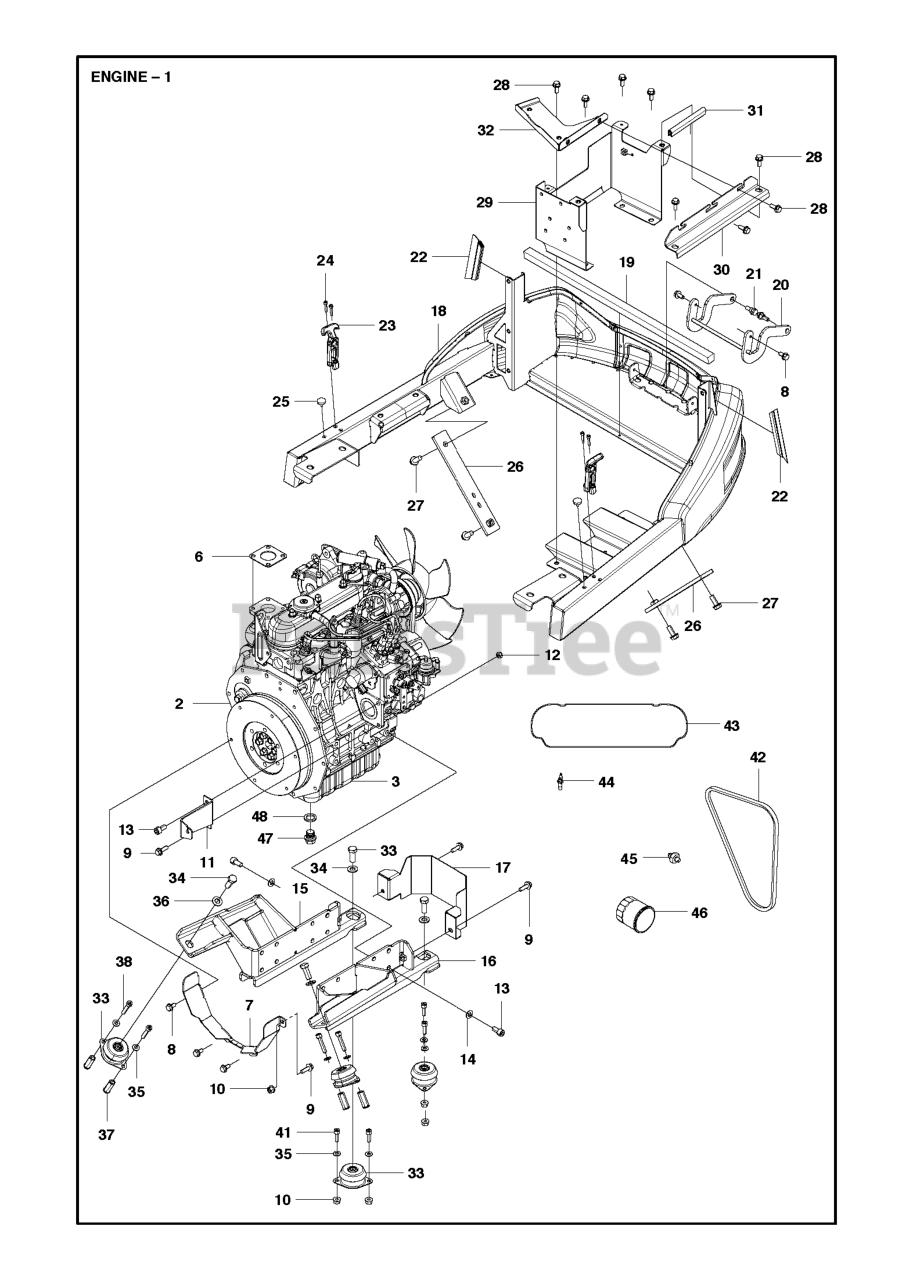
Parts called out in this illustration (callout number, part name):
9	BOLT
10	NUT FLANGE
12	LOCKNUT M8
14	WASHER
24	SCREW IHSCM
34	Hex Head Capscrew, M12 X 1.75 X 30 DIN933ZP
35	WASHER BRB 8.4X17
36	WASHER - M12
